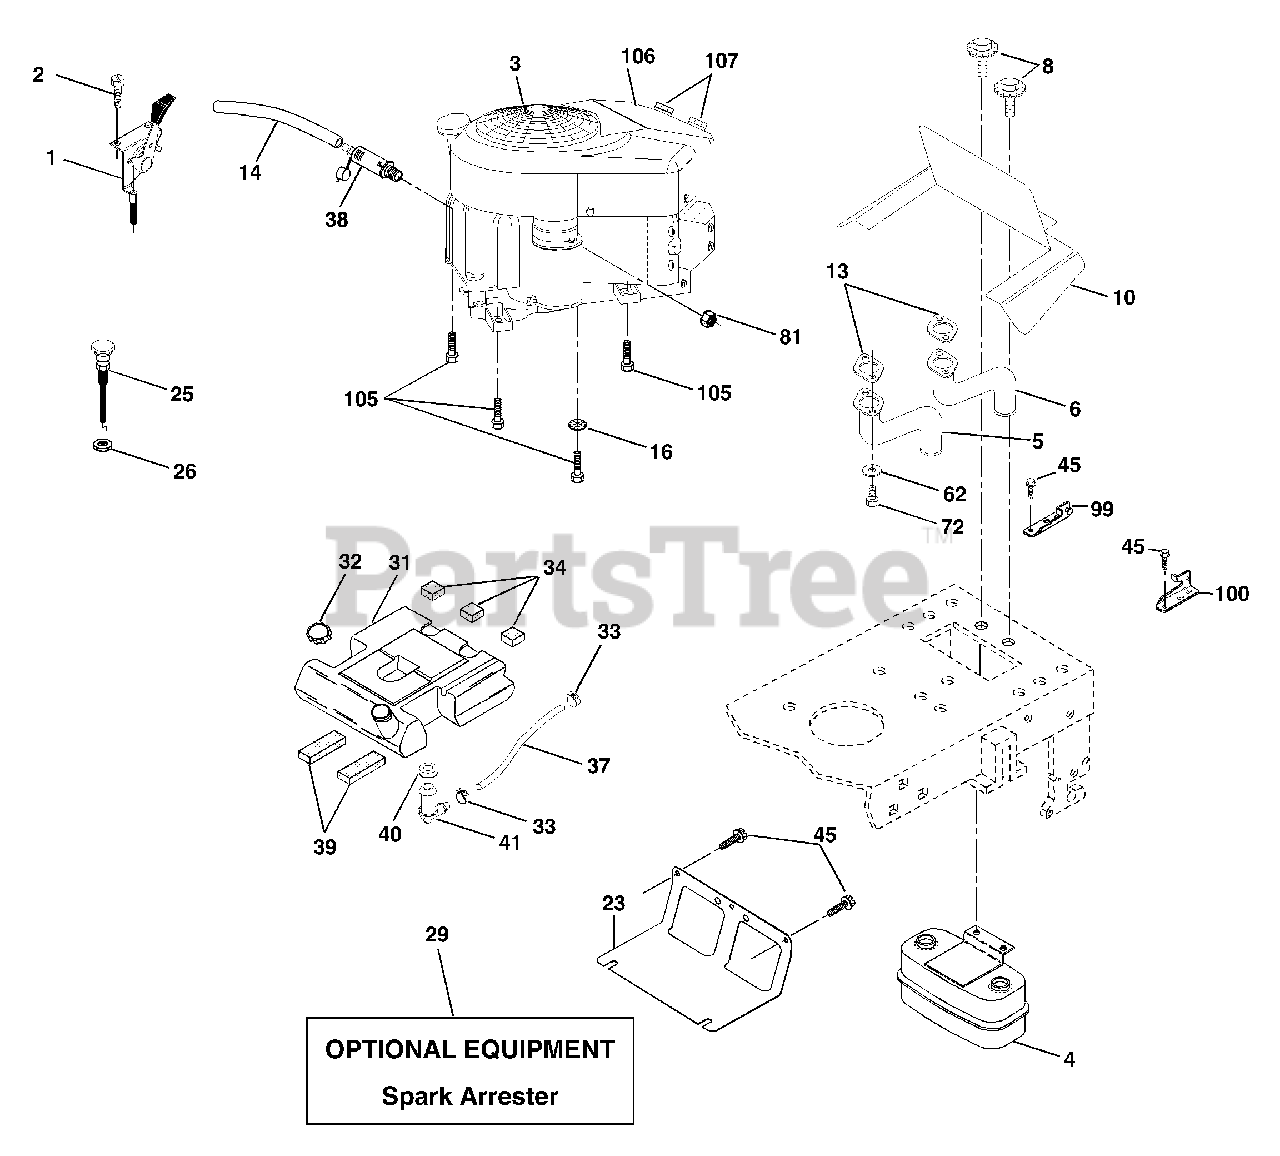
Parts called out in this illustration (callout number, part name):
1	Control, Throttle
2	Screw, Hex Head, Thread Cutting 1/4-20 x 5/8
4	Muffler
5	Tube, Exhaust, LH
6	Tube, Exhaust, RH
8	Bolt 5/16-18 UNC x 3/4 w/Sems
10	Shield, Heat
13	Muffler Gasket
14	Tube Drain Oil Easy
16	Washer, Lock, External Tooth 3/8
23	Shield, Browning / Debris Guard
25	Choke Control
26	Nut, Keps 3/8-24 UNF
29	Kit, Spark Arrestor
31	Tank Fuel 3 50 Rear
32	Cap Fuel Gauge
33	Clamp, Hose
34	Pad, Spacer
37	Line, Fuel
38	Plug Drain Oil Easy
39	Pad, Idler
40	Bushing
41	Stem, Fuel Tank
45	Screw Hex wsh Thdrol 3/8-16 x 3/4
62	Washer Lock 5/16
72	Screw Hex Hd Cap 5/16-18 x 3/4
81	Nut Keps Hex 1/4-20 Unc
99	Bracket Asm Pivot Lh Raised
100	Bracket Asm Pivot Rh Raised
105	Screw 3/8-16 x 1
106	Control Cover
